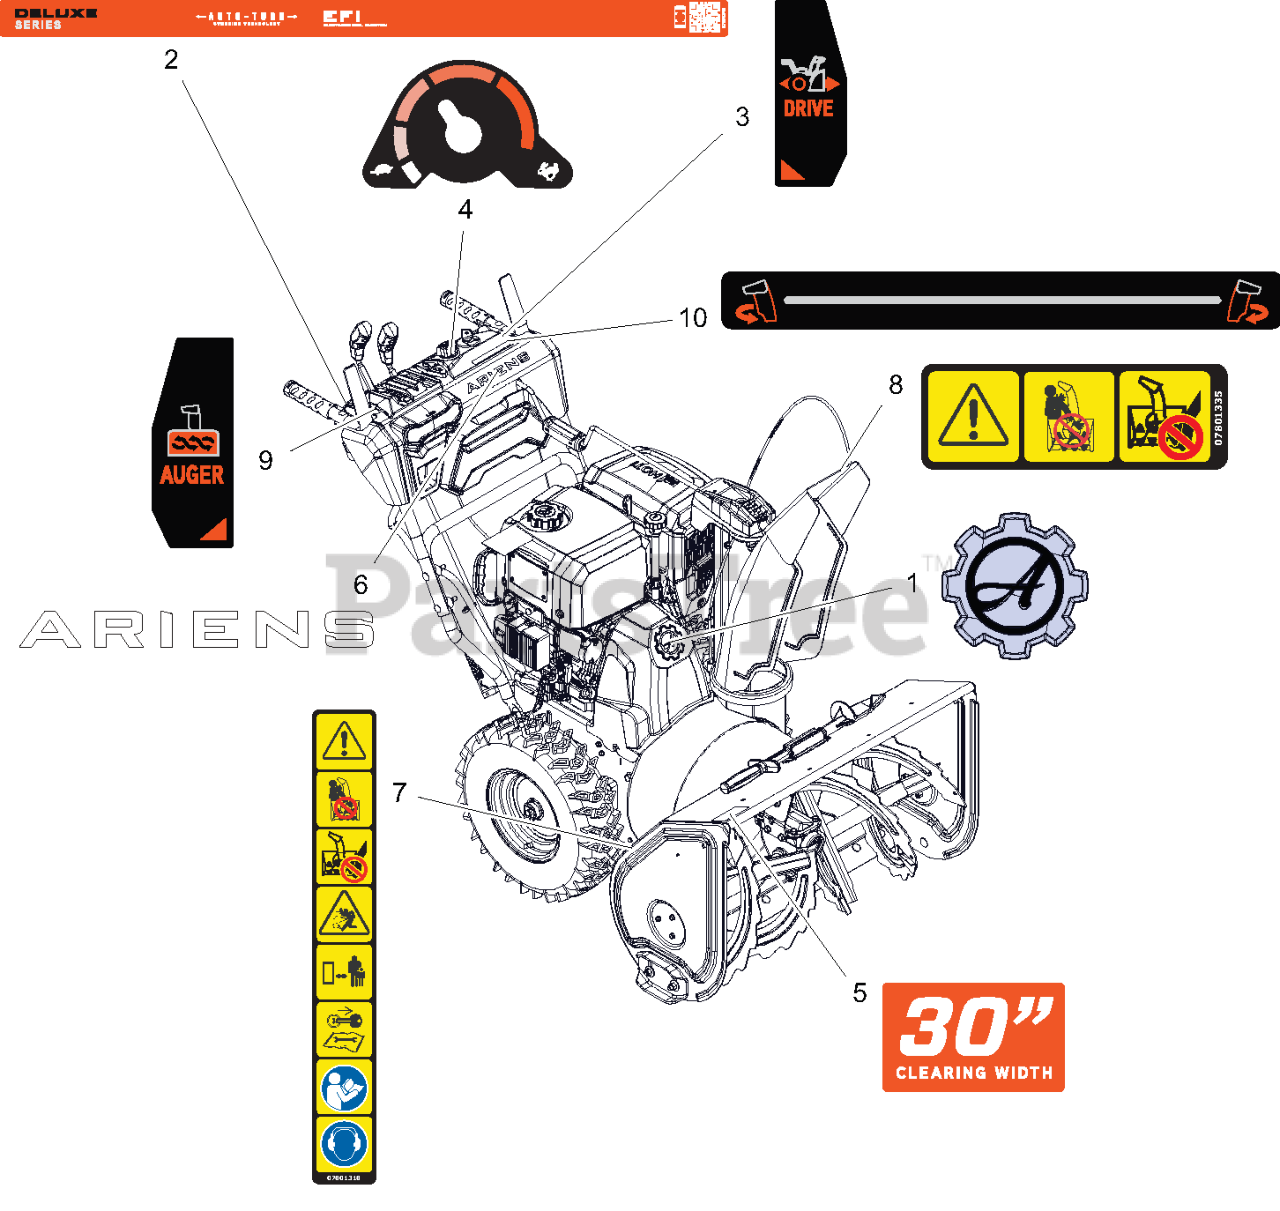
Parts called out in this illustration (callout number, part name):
1	DECAL- ARIENS GEAR BADGE
2	DECAL- DASH - DLX EFI
3	DECAL- CONTROL - DRIVE WHEEL
4	DECAL- CONTROL - EFI SPEED
5	DECAL- CLEARING - 30
6	DECAL- ARIENS - 7.46"
7	DECAL- SAFETY - DANGER
8	DECAL- DANGER
9	DECAL- CONTROL - AUGER
10	DECAL- CHUTE ROTATION
